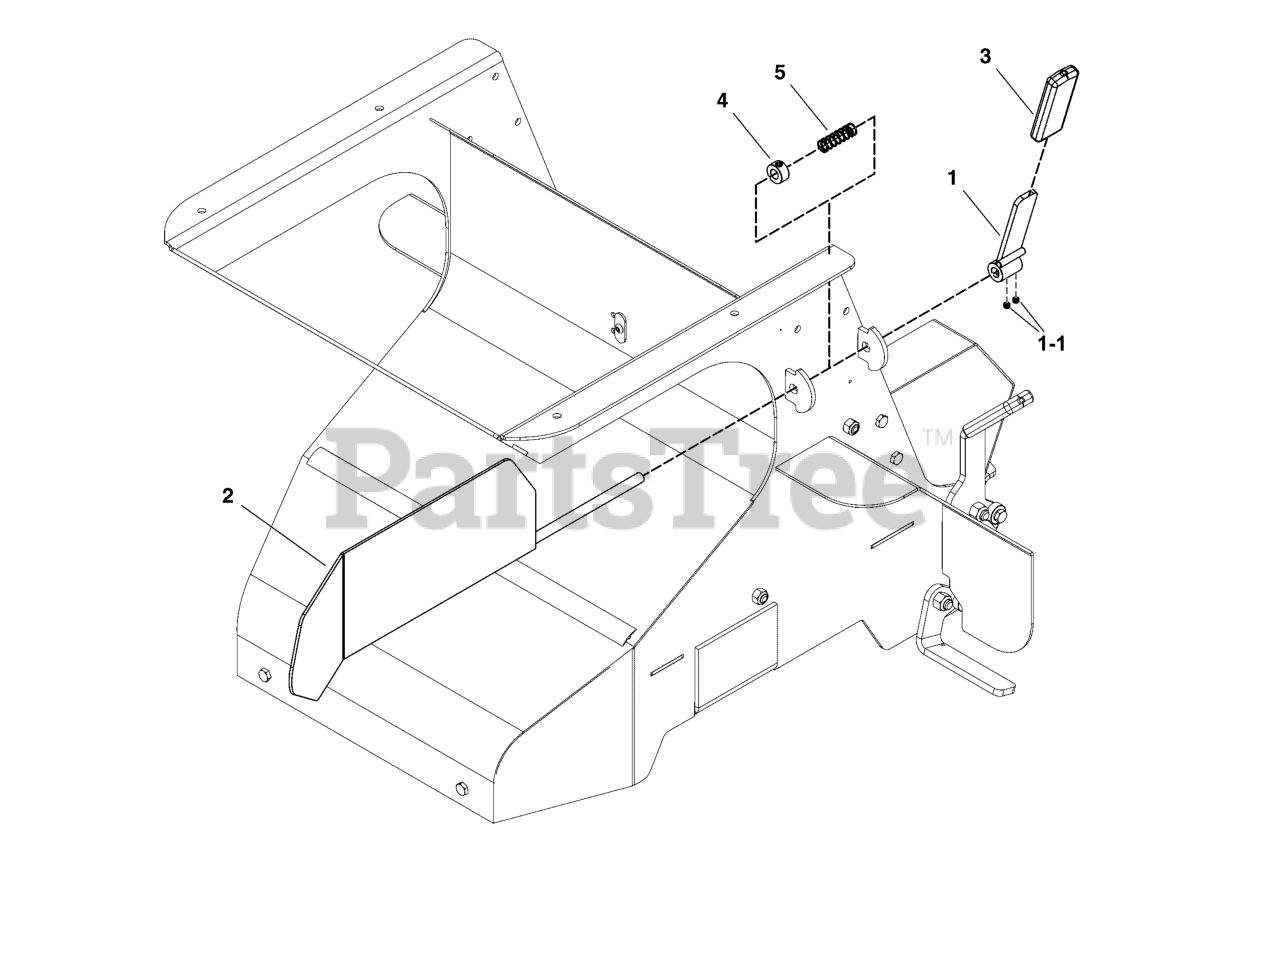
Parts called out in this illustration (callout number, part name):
1	WELD, HANDLE DIVERTER, ROVER
1-1	SET SCREW, 1/4"-20 X 3/16" Hex Socket
2	WELD, DIVERTER ROVER
3	GRIP, .188" X 1.00" ID X .150" THK CLSD CELL FOAM
4	COLLAR, SHAFT .375ID X .750OD X .375WD
5	SPRING, COMPRESSION .480" OD X 1.500 LONG SS
